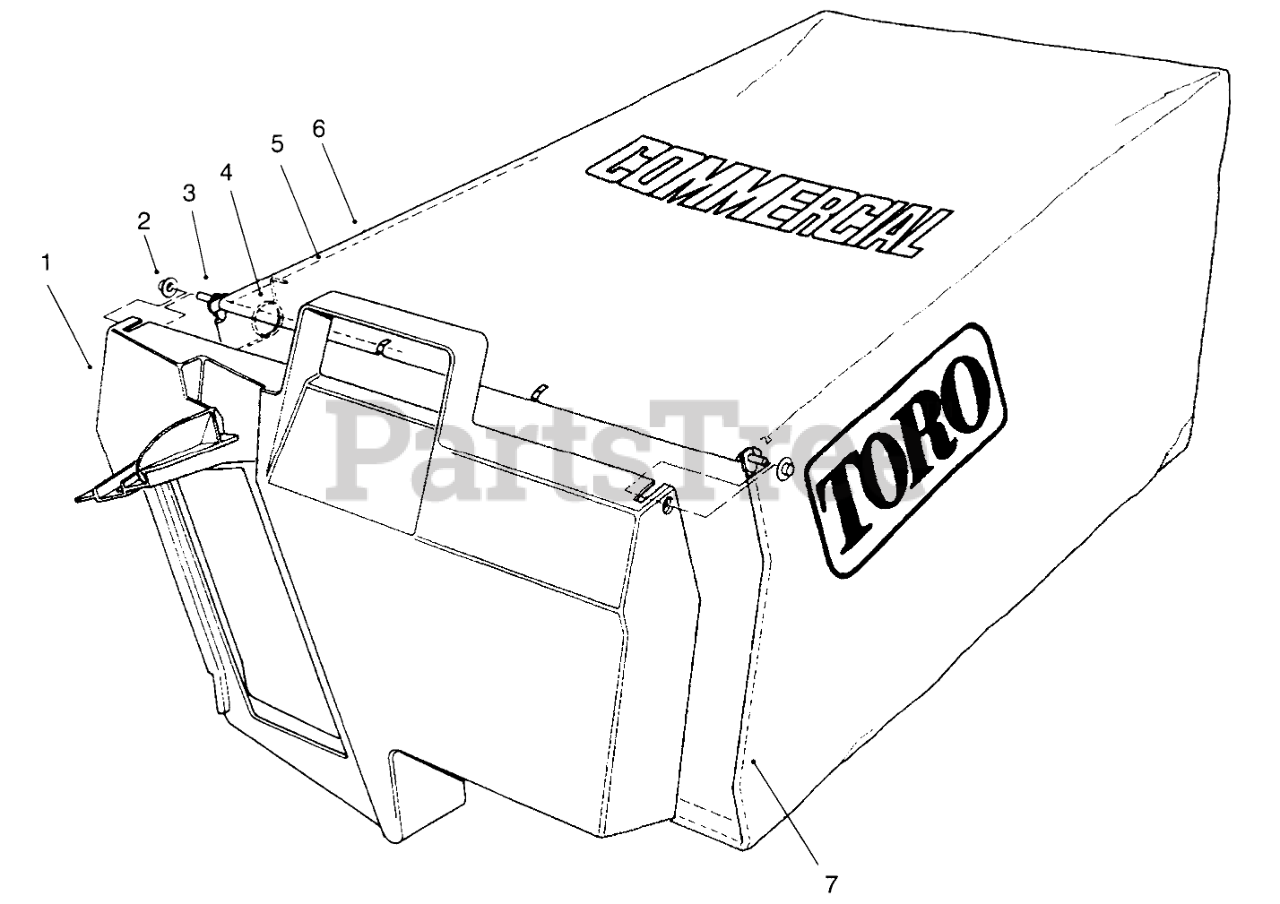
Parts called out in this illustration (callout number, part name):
1	DOOR-BAG, GRASS
2	NUT-PUSH
3	HINGE-DOOR, BAG
4	SPRING
5	FRAME-BAG, UPPER
6	Bag
7	FRAME-BAG
